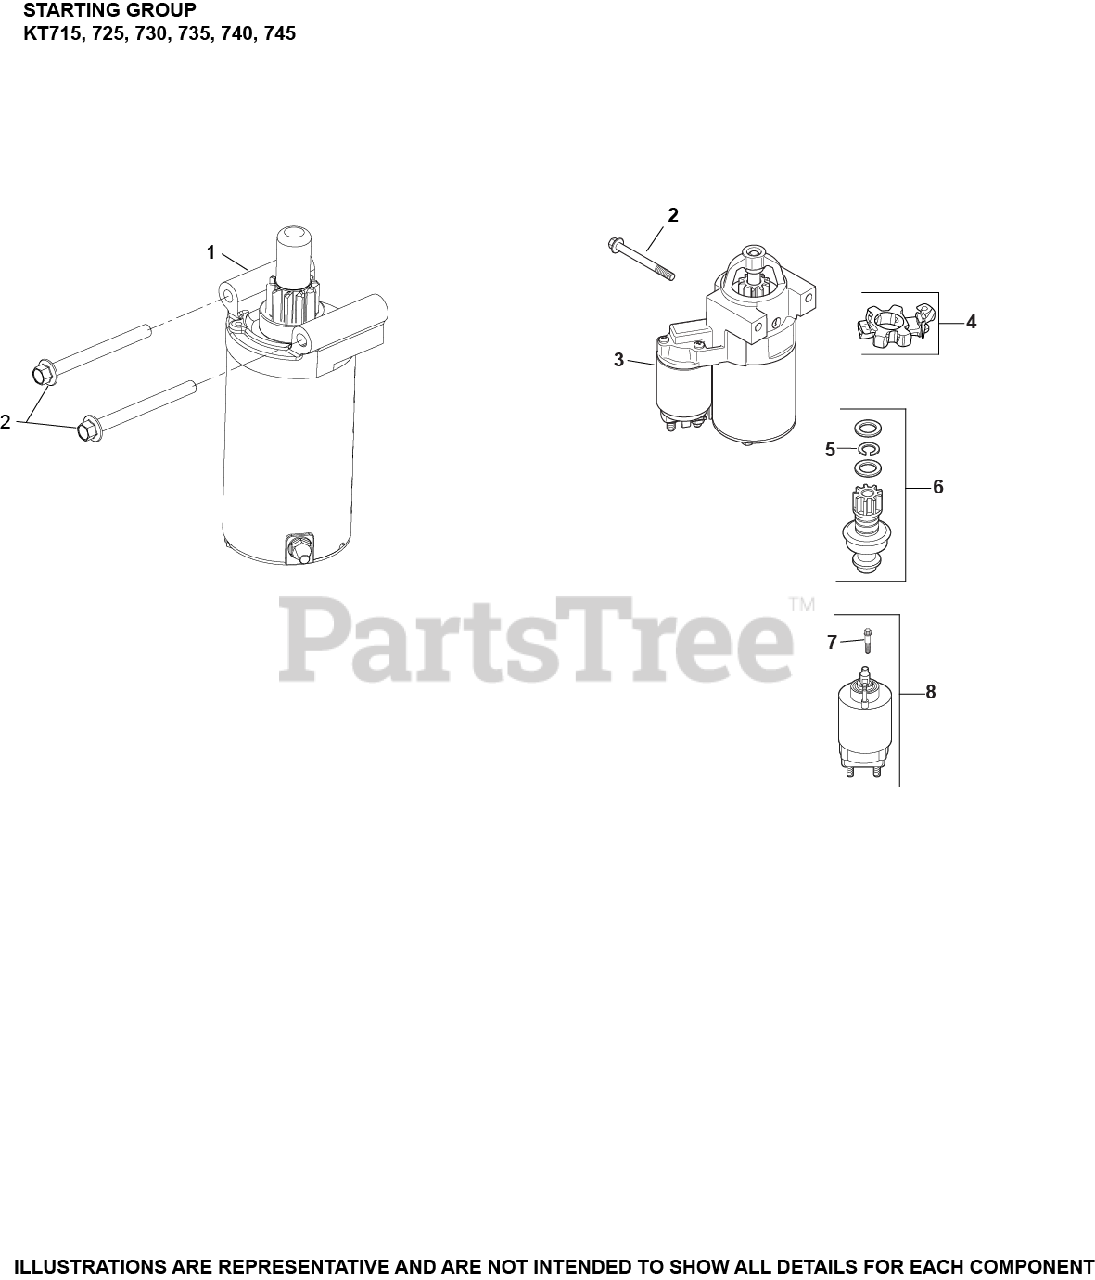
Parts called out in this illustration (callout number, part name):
2	SCREW, FLG M8X1.25X80
3	ELECTRIC STARTER - SOLENOID SHIFT USE 25 098 20-s
4	KIT, BRUSH HOLDER
5	RING, RETAINING
6	KIT, STARTER PINION
7	SCREW, EXTERNAL TORX HEAD
8	KIT, SOLENOID
